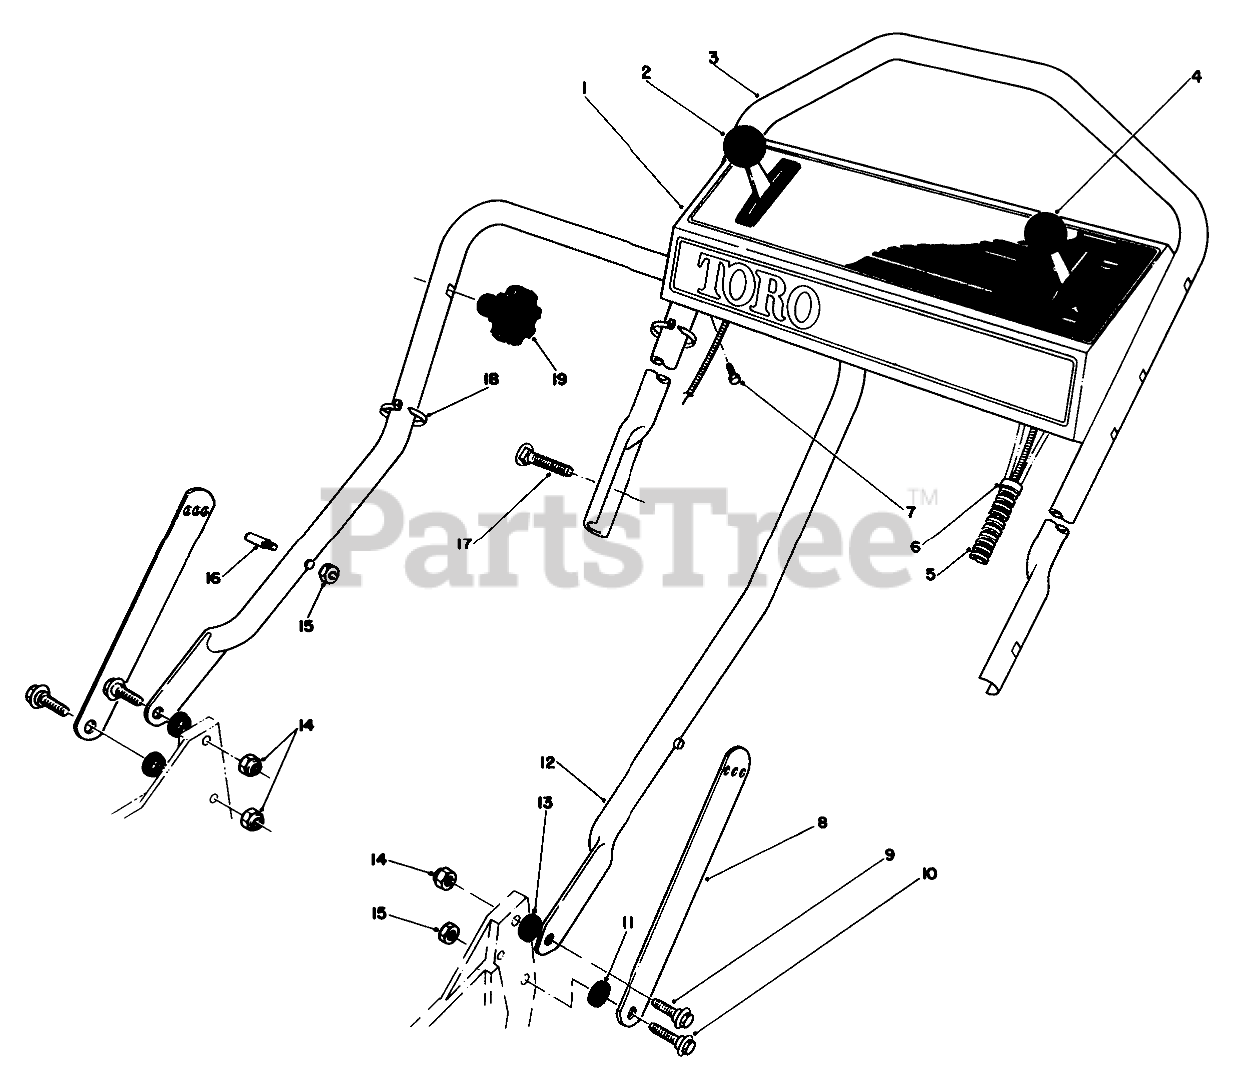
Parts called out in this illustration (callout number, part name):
1	Panel-Control
2	SERVICE THROTTLE CONTRO
3	Handle-Upper
4	Decal-Control Panel
5	CONTROL CABLE COVER
6	FITTING-RING
7	SCREW-HWHTF
8	Handle Latch
9	SCREW-SHOULDER
10	SCREW-SHOULDER
11	SPACER
12	LOWER HANDLE ASM
13	SPACER
14	NUT-LOCK, NI
15	NUT-LOCK, NI
16	HANDLE PIN
17	5/16-18 X 2 HNDLE SCREW
18	TIE-CABLE
